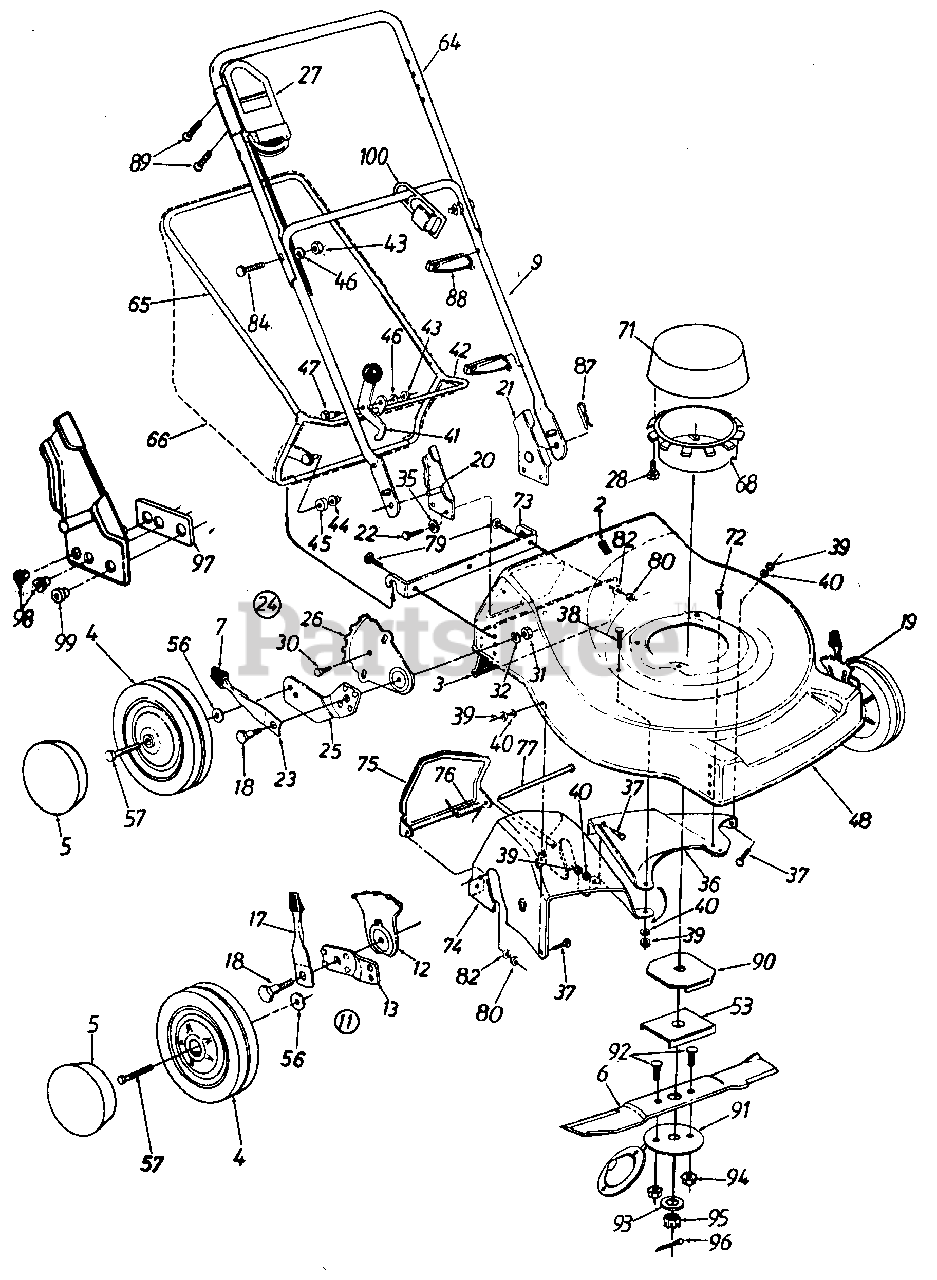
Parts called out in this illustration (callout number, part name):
3	Rear Flap Ass'y.
4	Wheel Ass'y. Comp.
5	Hub Cap
6	20" Blade
7	Spring Lever Knob
9	Lower Handle
11	Front Height Adj. Ass'y.-R.H.
12	Front Index Plate
17	Spring Lever w/Knob
18	Shld. Bolt .50" Dia. x .375
19	Front Height Adj. Ass'y.-L.H.
20	Handle Brkt. Ass'y.-R.H.
21	Handle Brkt. Ass'y.-L.H.
22	Hex Wash. Hd. Tap Scr. 1/4-20 x 1 " Lg.
23	Spring Lever
24	Rear Height Adj. Ass'y.-R.H.
25	Rear Pivot Bar-R.H.
26	Rear Index Plate
27	Cord and Switch Ass'y.- Complete
28	Screw #10-16 x .75" Lg.
30	Hex Wash. Hd. Tap Scr. 1/4 x .62" Lg.
31	Hex Nut 3/8-16 Thd.
32	Bell-Wash. 3/8" I.D.
35	Fl-Wash. .266" I.D. x .625" O.D.
36	Rear Chute Baffle-L.H.
37	Carr. Bolt 1/4-20 x 50n Lg.
38	Hex Bolt 1/4-20 x .88n Lg.
39	Hex Nut 1/4-20 Thd.
40	L-Wash. 1/4" I.D.*
41	Cam Lever Grip Ass'y.
42	Grass Catcher Lower Frame
43	Hex Nut 5/16-18 Thd.
44	Push Cap 3/8" Rod
45	Plastic Roller
46	L-Wash. 5/16" I.D.*
47	Shld. Bolt .437" Dia. x .180"
56	Bell-Wash. .400" I.D. x .88"
57	Axle Bolt
64	Upper Handle
65	Grass Catcher Upper Frame
66	Grass Bag w/Flip Top
68	Motor Cover Bottom
71	Motor Cover Top
72	Hex Self-Tap Scr. 1/4-20 x .75"
73	Grass Catcher Hitch Brkt.
74	Rear Chute Baffle-R.H.
75	Chute Door
76	Torsion Spring
77	Hinge Pin
79	Carr. Bolt 1/4-20 x .75" Lg.
80	Hex Sems Nut 1/4-20 Thd.
82	Fl-Wash. .281" I.D. x 1.25"
84	Curved Carr. Bolt 5/16-18 x 1.38" Lg.
87	Hairpin Cotter
88	Cable Tie
89	Self Tap Scr. #7 x 1" Lg.
90	Blade Adapter
91	Blade Insulator
92	Carriage Bolt 5/16-18 x .75" Lg.
93	Fl-Wash. .516" I.D. x 1.5" (H.T.)
94	Hex Keps Nut 5/16-18 Thd.
95	Slotted Hex Nut 1/2-20 Thd.
96	Cotter Pin 1" Lg.
97	Insulator Strip
98	Insulator Shield
99	Insulafor Shield
100	Cord Restraint
